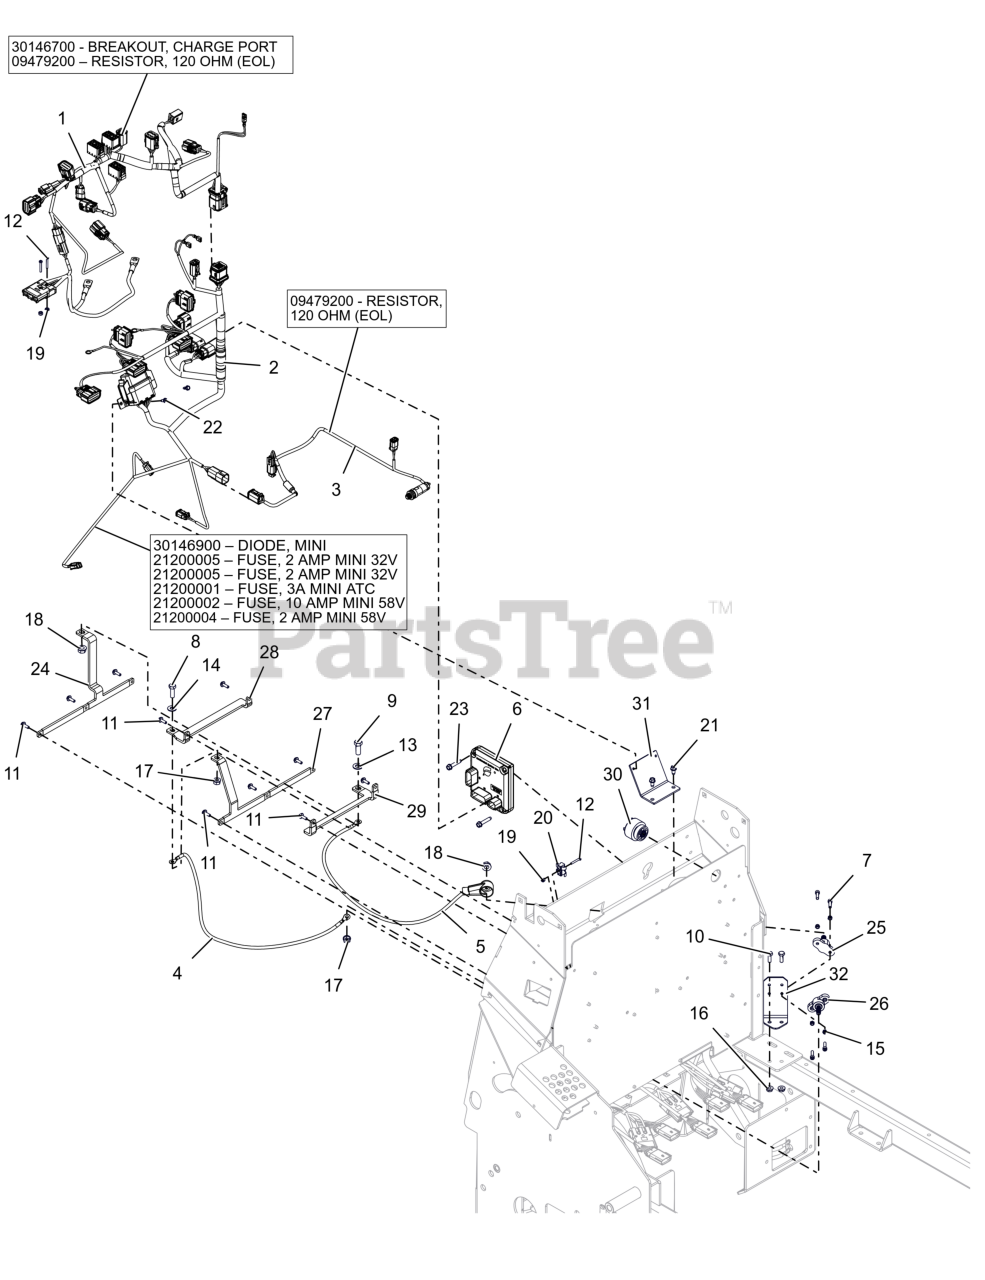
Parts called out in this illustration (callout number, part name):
1	HARNESS- ELECTRICAL -PSEV
1	BREAKOUT, CHARGE PORT
1	EOL RESISTOR
2	HARNESS- ELECTRICAL -PSEV
2	DIODE- MINI
2	FUSE- 2 AMP MINI 32V
2	FUSE, 3A MINI ATC
2	FUSE, 10 AMP MINI 58V
2	FUSE- 2 AMP MINI 58V
3	HARNESS- ELECTRICAL -PSEV
3	EOL RESISTOR
4	CABLE- NEG 26"
5	CABLE- POS 26"
6	KIT, PSEV VCM RD REPLACE
7	SCR, SKH M5-.8X20 12.9ZC120
8	BLT,HEX .31-18X1.00 G5 ZCC
9	BLT,HEX .38-16X1.00 G5 ZCC
10	BLT, HEX .25-20X.75 G5 ZCC
11	BLT,HEX M5-.8X16 EP30 G8.8 ZCC
12	SCR, PH PAN HD #6-32X1.000 ZCC
13	WSHR-FL-STL 0.406X0.812X0.065 UNPLATED
14	WSHR, FLT .312X.734X.065 ZCC
15	NUT,NYL M5-.8 G8.8 ZCC
16	NUT-LK-CTR-FLG .25-20 ZC120
17	NUT,LK-CTR-FLG .31-18 GF ZCC
18	NUT-LK-CTR-FLG .375-16 GF ZCC
19	@NUT-LK-NYL 6-32 W/INSRT YWZC
20	CLIP,T,.31-.38,
21	SCR-TAP .25-20X.50 HWH ZCC
22	SCR,TAP #10-24X.50 HWH TR ZCC
23	SCR-TAP .25-20X1.25 HWH ZCC
24	BAR, BUSS-POS
25	STUD, POSITIVE POWER
26	STUD, NEGATIVE POWER
27	BAR- BUSS -NEG
28	BAR- BUSS-NEG. WHL
29	BAR- BUSS -POS. WHL
30	ALARM- AUDIBLE
31	BRKT- FUSE BLOCK MTG
32	BRKT- BATTERY TERMINAL
